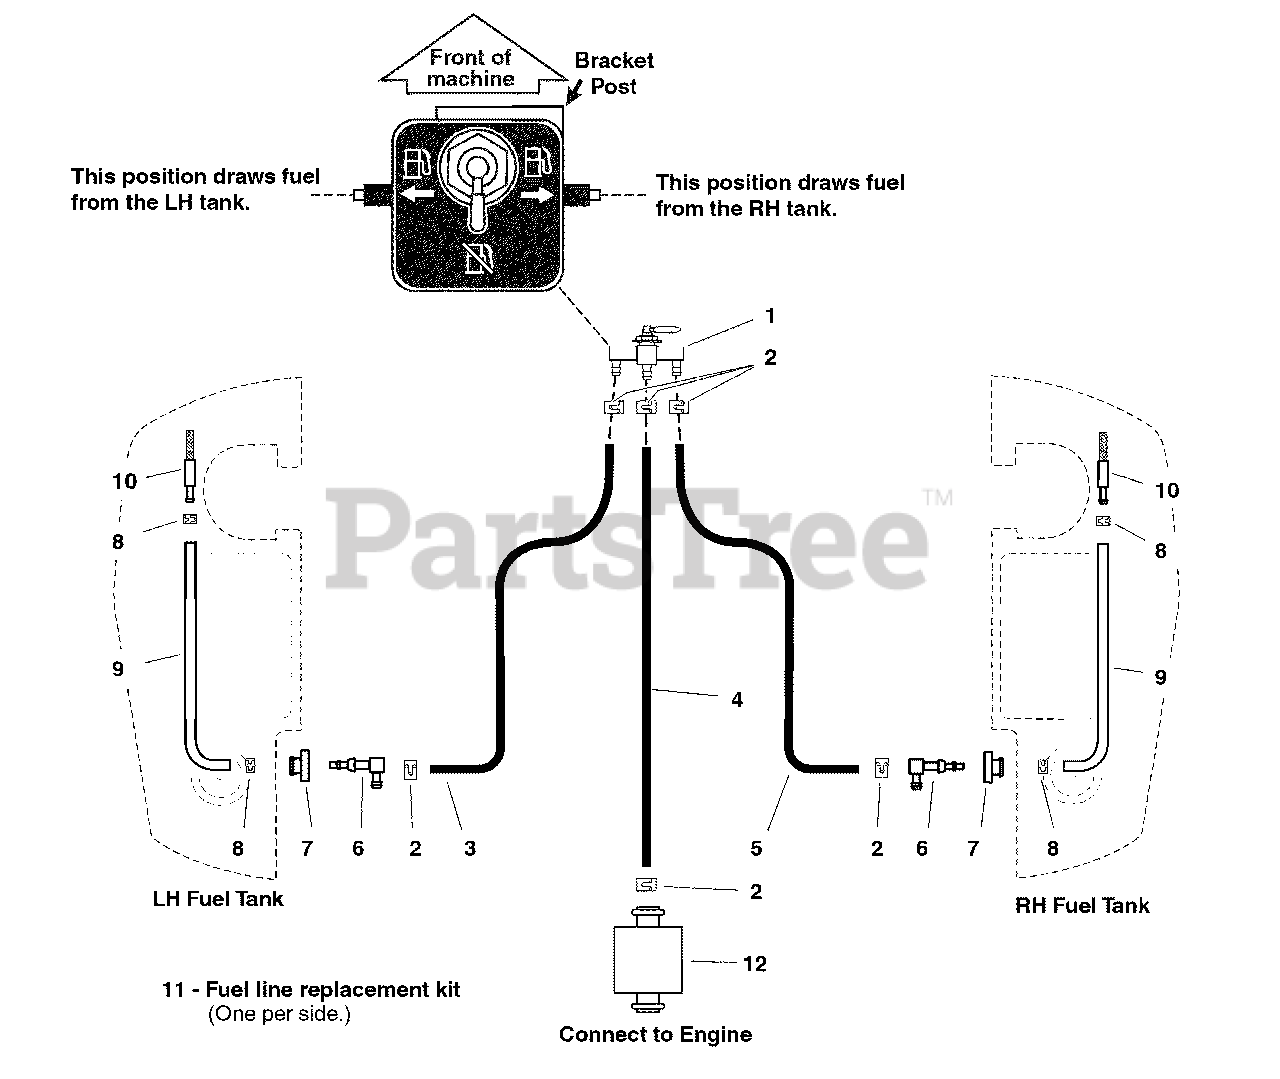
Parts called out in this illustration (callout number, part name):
1	VALVE, FUEL, STR. OUTLET
2	CLAMP, HOSE, EXTERNAL, 1/2 - RED
3	HOSE, 1/4" FUEL, 35.00"
4	HOSE, 1/4" FUEL, 16.00"
5	HOSE, 1/4" FUEL, 10.00"
6	ELBOW FITTING
7	BUSHING-FUEL TANK RED RUBBER (SV)
8	HOSE CLAMP, INTERNAL
9	HOSE 26"
10	SCREEN FITTING
11	FUEL LINE REPLACEMENT KIT
12	FUEL FILTER (SV)
